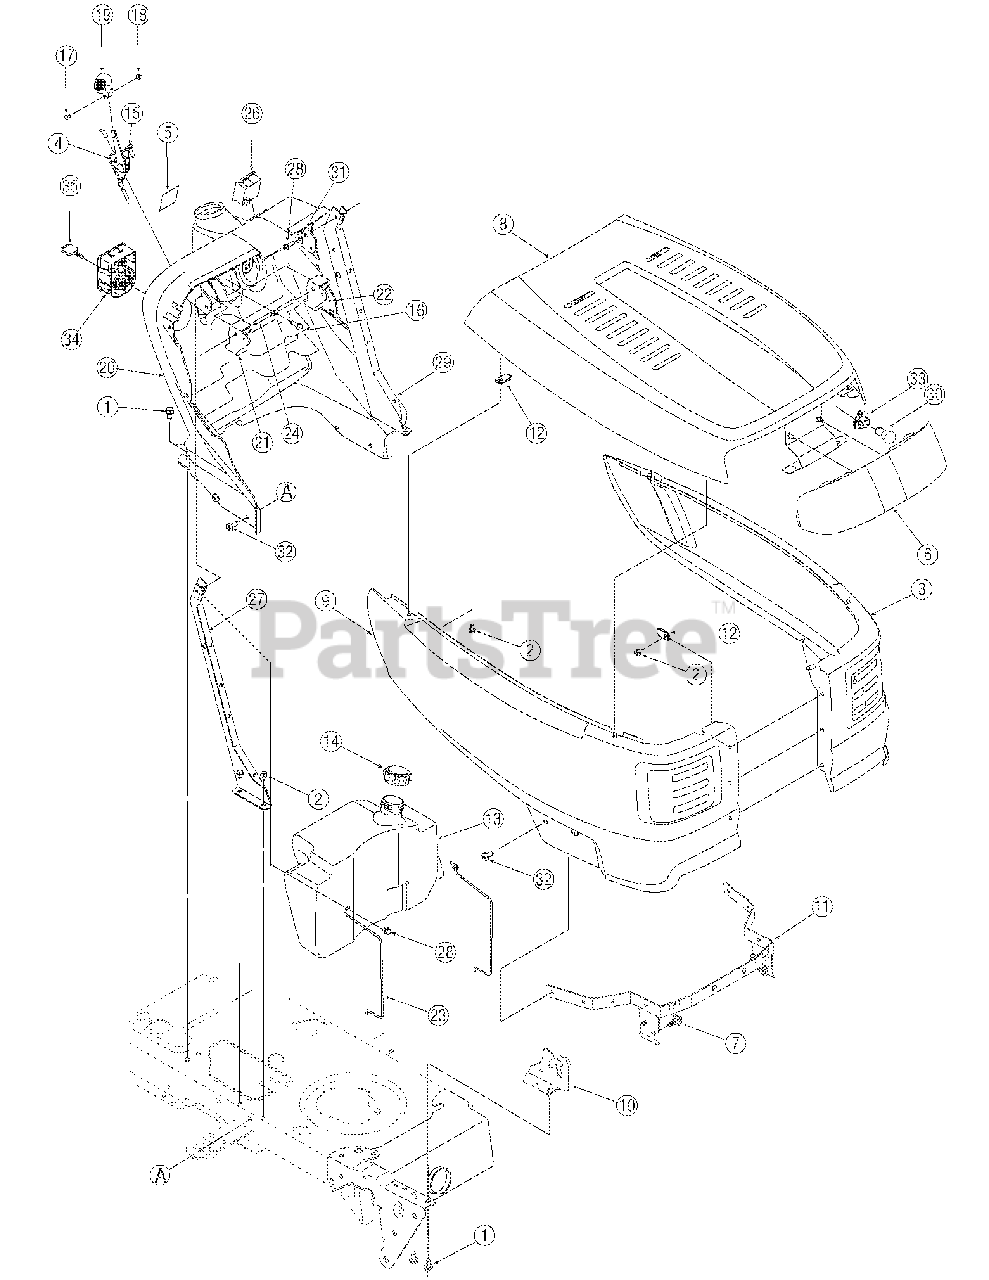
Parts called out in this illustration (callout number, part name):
1	Screw, 5/16-12 x.750
2	Self-tapping Screw, 1/4-20 x.5
5	Choke Plug
6	Headlight Lens
7	Shoulder Screw,.43 x.29
12	Speed Nut
13	Fuel Tank, Three Gallon
14	Fuel Cap
15	Screw, 1/4-14 x.625
16	Self-tapping Screw, 1/4-15 x.75
17	Truss Phillips Screw, #8-32 x .375
18	Hex Nut, #8-32
19	Throttle Control Knob
20	Dash Panel
21	Cruise Control Button
22	Parking Brake Button
23	Tank Support Rod
24	Brake/Cruise Pivot Rod
25	Headlight Wire Harness
26	Systems Ind. Monitor w/Ammeter
30	Lamp
31	Bell Washer,.265 x.75 x.062
32	Screw, 5/16-18 x.75
33	Headlight Socket
34	Ignition Switch
35	Ignition Key w/ plastic cover
35	Ignition Key w/o plastic cover
